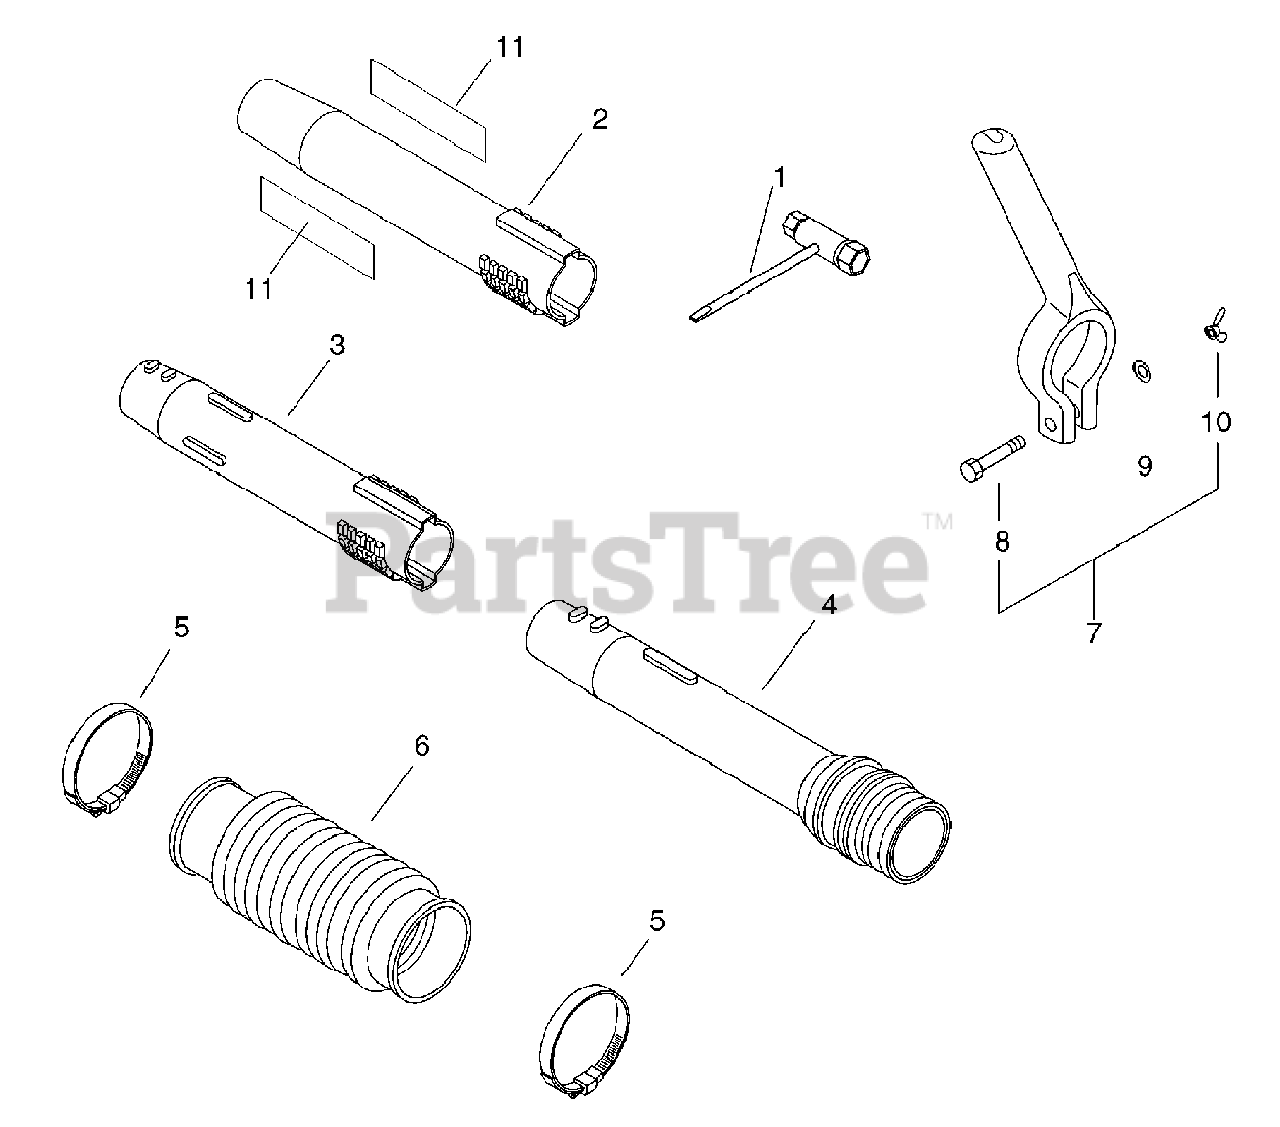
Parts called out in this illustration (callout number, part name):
1	T-WRENCH - 13X19mm
2	TUBE, BLOWER - STRAIGHT NOZZLE
3	TUBE, BLOWER - STRAIGHT
4	TUBE, BLOWER - SWIVEL
5	CLAMP, HOSE
6	TUBE, BLOWER - FLEXIBLE
7	HANDLE - FRONT
8	BOLT - 6X45
9	WASHER - 6
10	WINGNUT - 6
11	LABEL - ECHO
